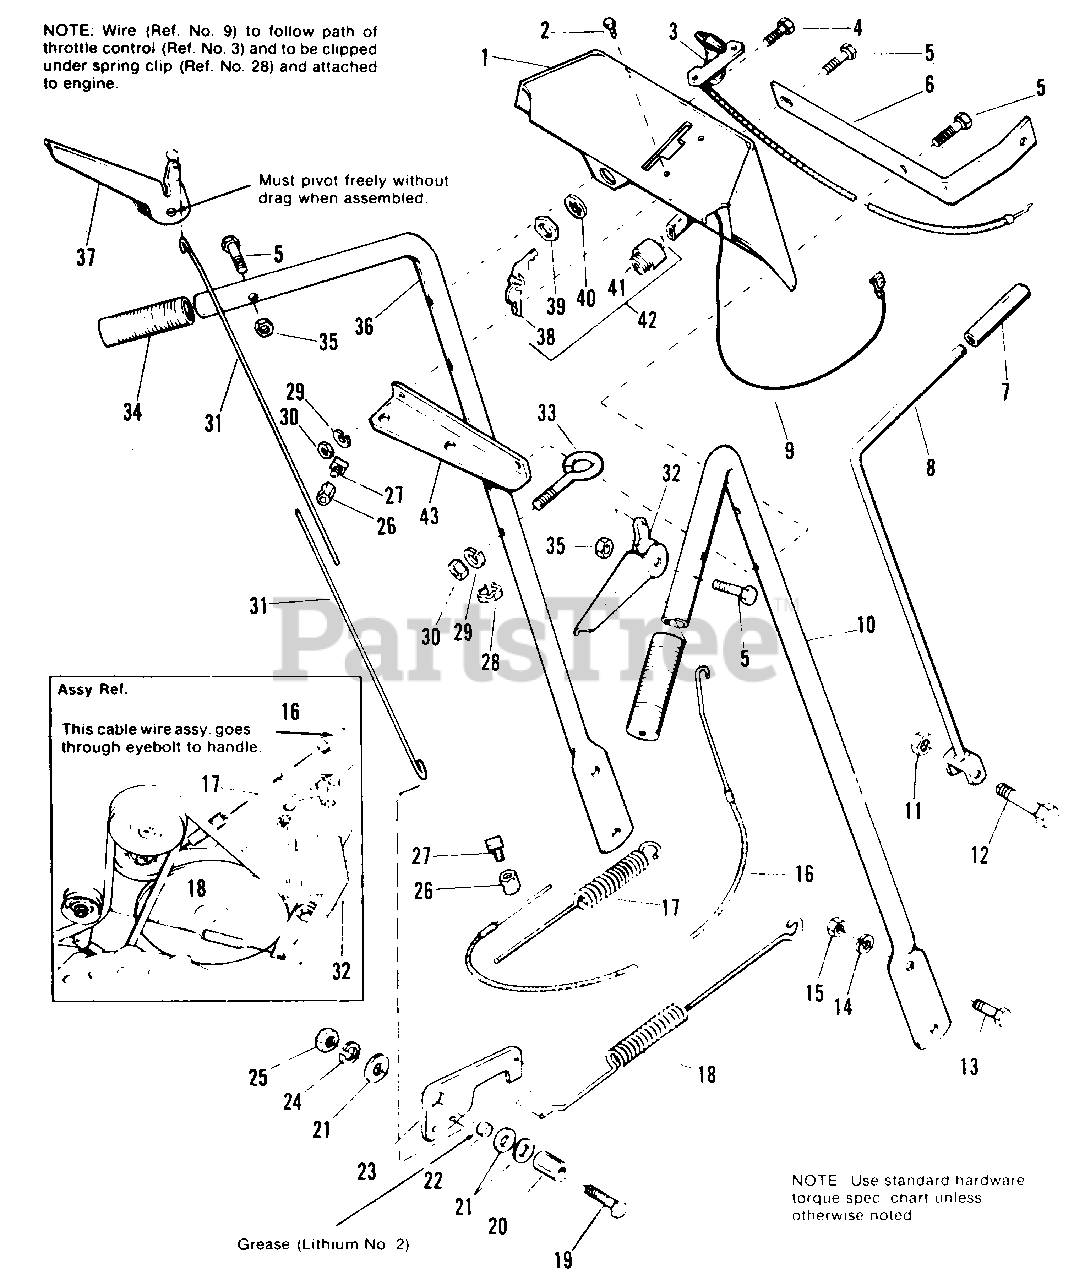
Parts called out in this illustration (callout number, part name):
1	HOUSING ASSY.
2	SCREW, Thd Forming, 1/4-20 x 1/2
3	CONTROL, Throttle (1690209, 1690255, 1690379 & 1690442 Only)
3	CONTROL, Throttle (1690380 Only)
4	CAPSCREW, Hex, 1/4-20 x 1-3/4
5	CAPSCREW, Hex, 1/4-20 x 1-1/2
6	SUPPORT, Bracket
7	HANDLE, Grip
8	ROD ASSY., Shift, Upper
9	WIRE ASSY.
10	HANDLE, R.H.
11	LOCKNUT, Hex, 5/16-18
12	CAPSCREW, Hex, 5/16-18 x 2
13	CAPSCREW, Hex, 5/16-18 x 7/8
14	LOCKWASHER, 5/16
15	NUT, Hex, 5/16-18
16	CABLE & WIRE ASSY.
19	CAPSCREW, 7/16-14 x 2-3/4
21	WASHER, Plain, 3/8
23	ARM, Pivot
24	LOCKWASHER, 7/16
25	NUT, Hex, 7/16
26	CLAMP, Wire
27	SCREW, Sq Hd., #10-24 x 5/8
28	CLIP, Spring
29	LOCKWASHER, Spring, 1/4
30	NUT, Hex, 1/4-20
31	WIRE, Control
32	GRIP, Clutch, R.H.
33	BOLT, Eye
35	LOCKNUT, Hex, 1/4-20
36	HANDLE, L.H.
37	GRIP, Clutch, L.H. Auger Drive
38	KEYS & RING ASSY. (2 Keys)
39	NUT, Hex, 5/8
40	LOCKWASHER, Internal Tooth, 5/8
41	SWITCH (See Ref. No. 42)
43	GUIDE, Rod
